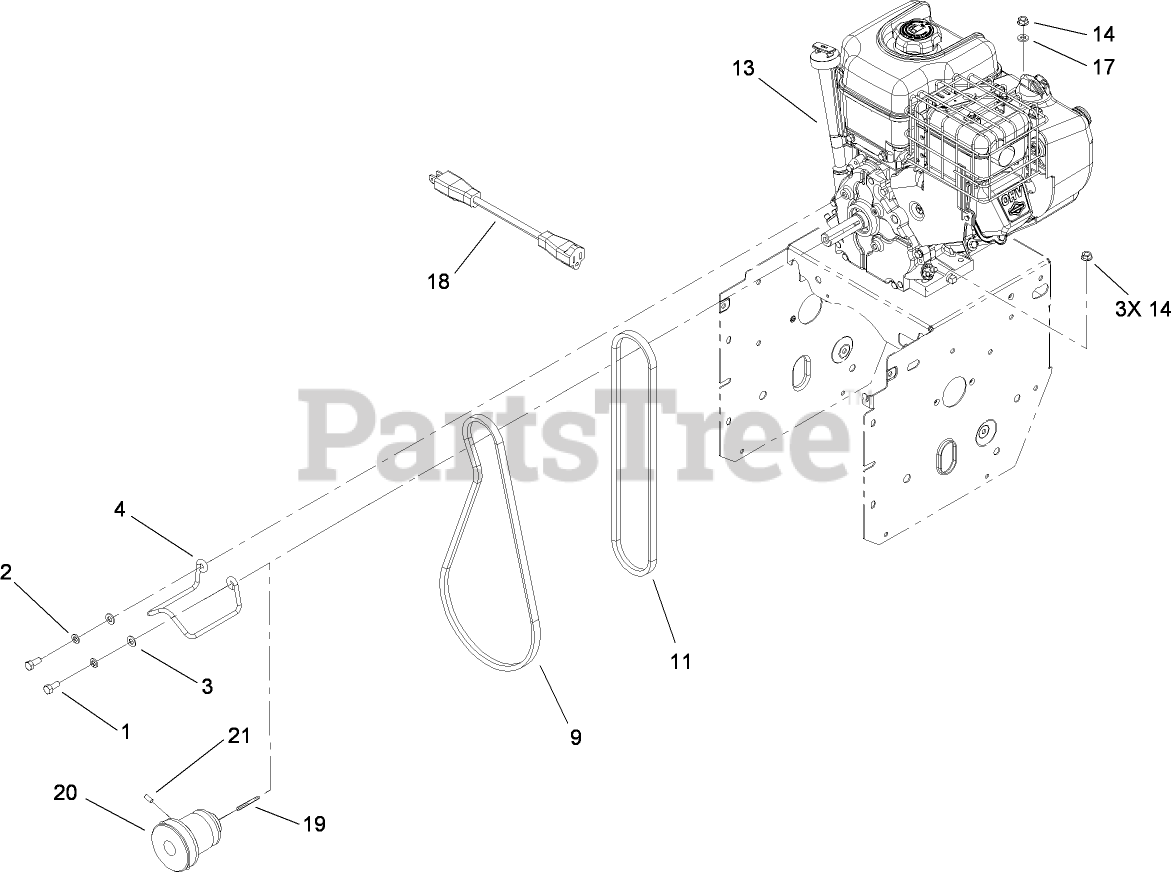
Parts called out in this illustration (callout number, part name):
1	SCREW-HH
2	WASHER-LOCK
3	WASHER-PLAIN
9	BELT-V
11	V BELT-TRACTION
13	Loose Parts Package
14	NUT-HF
17	WASHER-FLAT
18	CORD-EXTENSION (only on: 38078)
19	KEY-SQUARE
20	PULLEY-ENGINE
21	SCREW-SET, HSH
